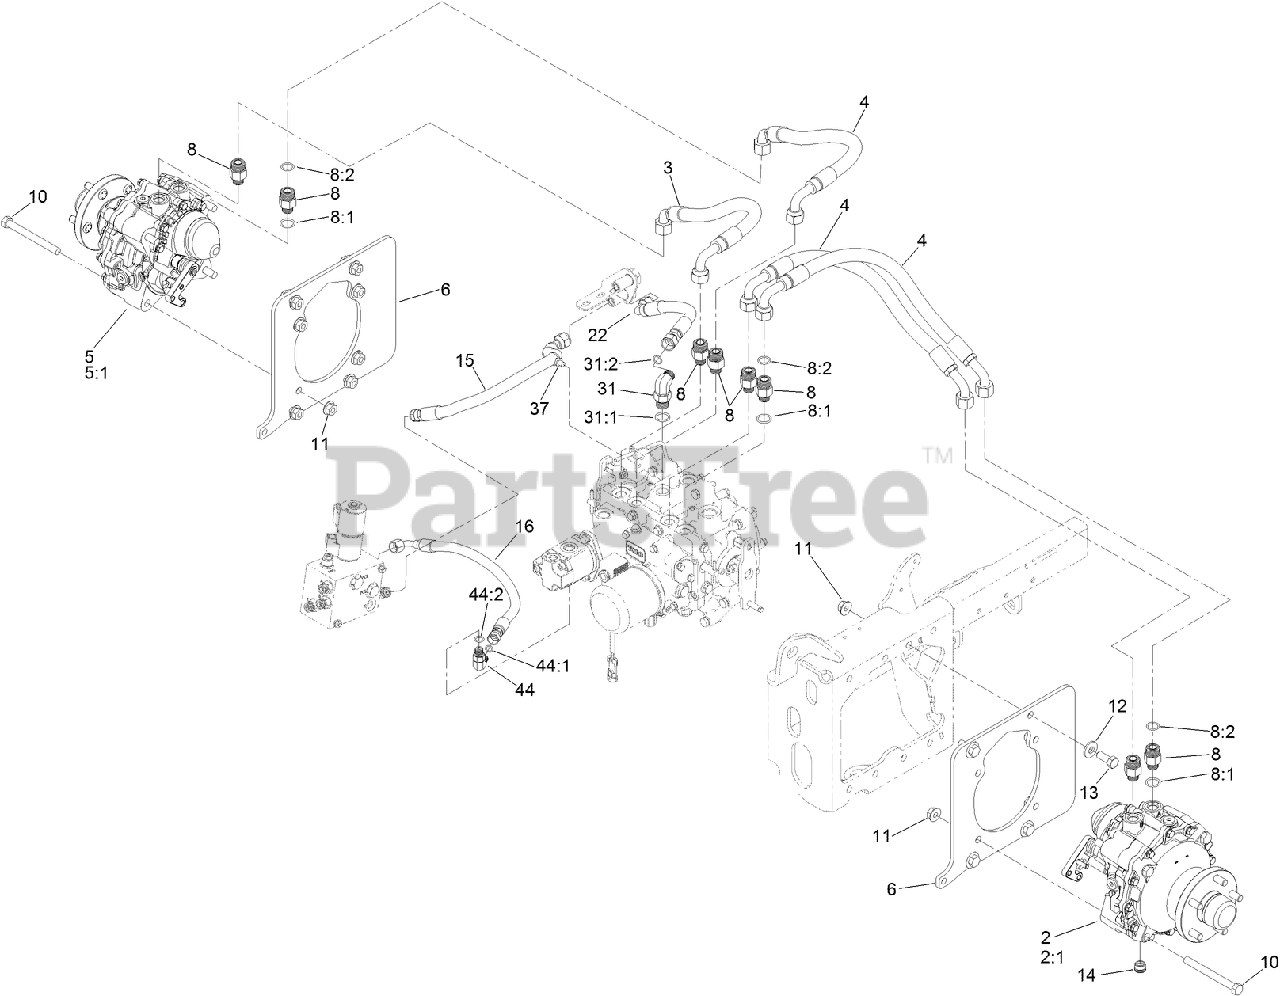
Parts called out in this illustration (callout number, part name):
2	MOTOR-HYD, LH
2:1	5 STUD WHEEL HUB KIT
3	HOSE ASM
4	HOSE ASM
5	MOTOR-HYD, RH
5:1	5 STUD WHEEL HUB KIT
6	PLATE-MOTOR
8	FITTING-STRAIGHT
8:1	O-RING
8:2	O-RING
10	SCREW-HH
11	NUT-HHF
12	WASHER-SPRING
13	SCREW-HH
14	PLUG-MAGNETIC
15	HOSE ASM
16	HOSE ASM
22	HOSE ASM
31	FITTING-ELBOW, 90 DEG
31:1	O-RING
31:2	O-RING
37	CLIP-TIE
44	FITTING-ELBOW, 90 DEG
44:1	O-RING
44:2	O-RING
